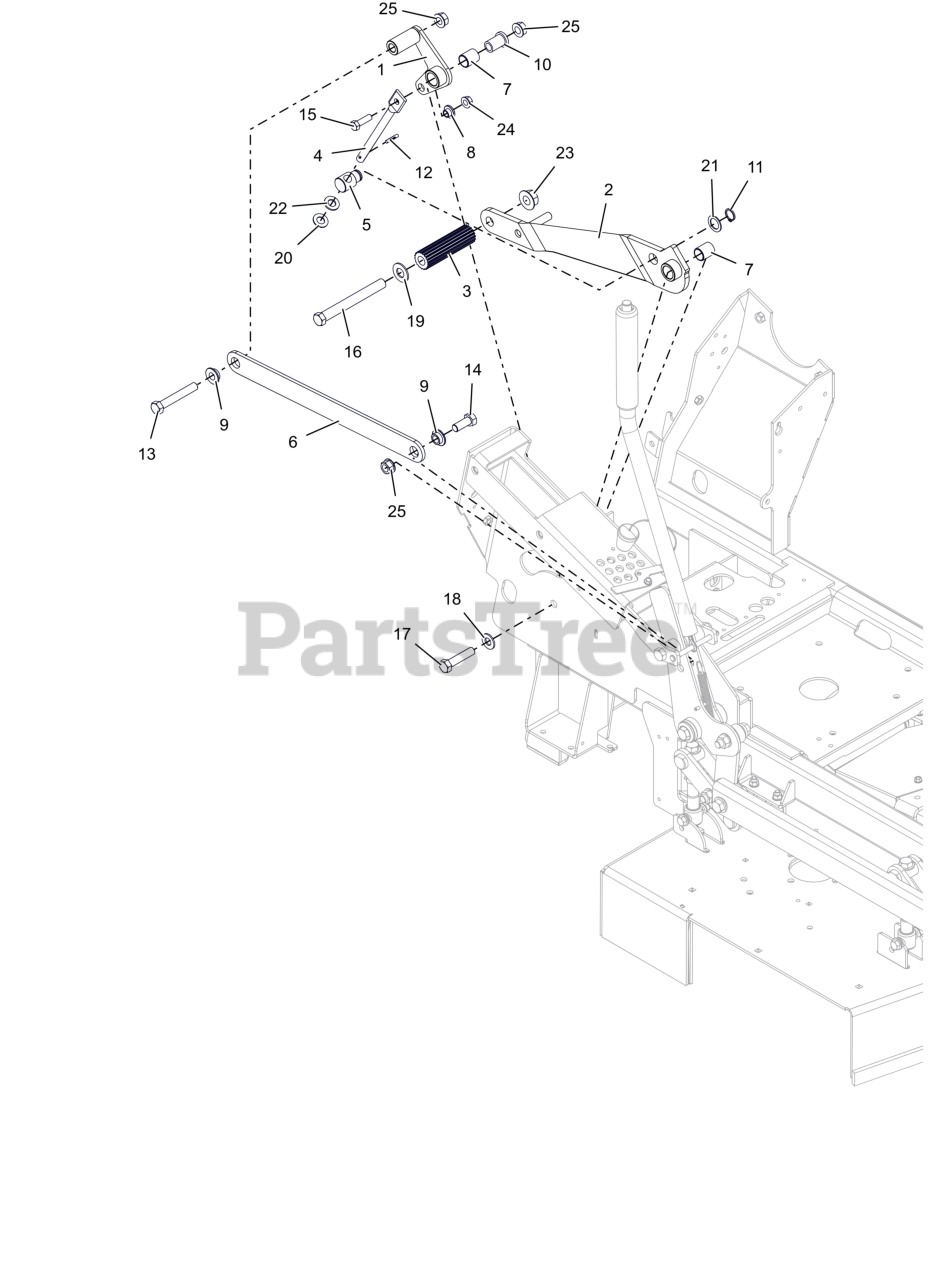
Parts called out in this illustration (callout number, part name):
1	WLDMT- PIVOT BRKT
2	WLDMT, DECK LIFT FOOT ASSIST (BLACK)
3	ROD, FOOT PEDAL (BLACK)
4	LINK, HOC FOOT
5	TRUNNION-DECK LIFT FOOT ASSIST
6	LINK, DECK LIFT FOOT ASSIST (BLACK)
7	BRG, .750 X .875 X 1.000
8	BSHG-FLG .385X.500X.875X.406
9	BSHG, FLANGE .515X.750X.420X1.12
10	BSHG-FLG .515X.746X1.290X1.000
11	RG-RTNG-EXT .689X.078
12	PIN-GRV .188X1.00 TP E
13	BLT,HEX .50-13X3.25 G5 ZCC
14	BLT,HEX .50-13X1.25 G5 ZCC
15	BLT, HEX .38-16X1.25 G5 ZCC
16	BLT, HEX .62-11X5.50 G5 FBP
17	BLT, HEX .50-13X2.25 G5 ZCC
18	WSHR,FLT .531X1.062X.095 ZCC
19	WSHRFLT 5/8SAE CARBHARD FBP
20	WSHR, FLT .531X1.00X.063 ZCC
21	WSHR, FLT .754X1.125X.062 ZCC
22	WSHR, RUBBER .531 X 1.000 X .094
23	NUT,FLG-TOP LK .625-11 FBP
24	NUT-LK-CTR-FLG .375-16 GF ZCC
25	NUT-LK-CTR-FLG .500-13 GG ZCC
